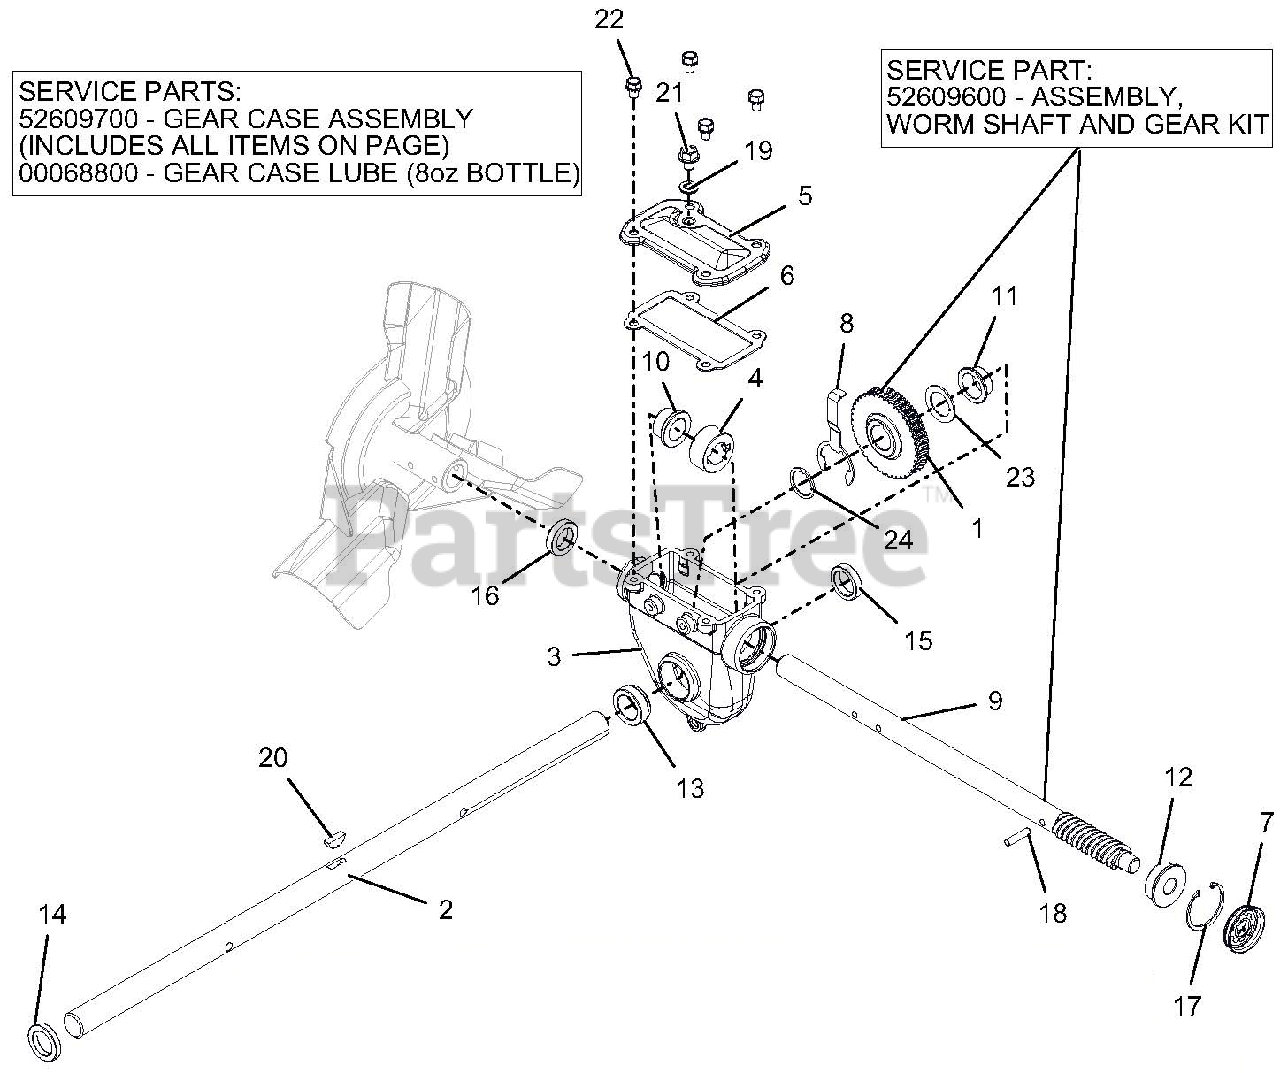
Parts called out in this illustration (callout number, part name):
1	WORM GEAR
2	SHAFT, RAKE-28"
3	GEARCASE, LARGE MACHINED
4	THRUST COLLAR, .875"ID SLIPFIT
5	COVER, TOP - LARGE IRON
6	GASKET, TOP - LARGE GEARCASE
7	COVER, GEAR CASE 1.75"
8	BUSHING RETAINER, LARGE
9	SHAFT, WORM - PRO
10	BSHG-FLG .879X1.128X.75X1.45
11	BSHG-FLG 1.006X1.128X.555X1.45
12	BSHG-FLG .628X1.503X.58X1.725
13	BSHG-FLG LARGE, RIGHT
14	SEAL-OIL .999X1.500X.250 TBC29
15	SEAL-OIL .999X1.375X.312 TBC29
16	SEAL-OIL .873X1.375X.312 TBC29
17	RG-RTNG-INT 1.750X.062
18	PIN-STR .250X1.12 6150
19	WSHR-BND-SEAL .38X.75X.11 GALV
20	KEY-WDRF .25X.875 HRD #A
21	@SCR-ROLOK .38-16X.50 HWH YWZC
22	BOLT, SEMS .31-18X.50 GR5 YWZC
23	WSHR-FL-STL 1.010X1.505X.062YZ
24	WSHR-FL-STL 1.010X1.250X.068YZ
25	GEAR CASE, 28" IRON PRO TOP-LD
26	ARIENS L3 LUBE, 8 OZ BOTTLE
